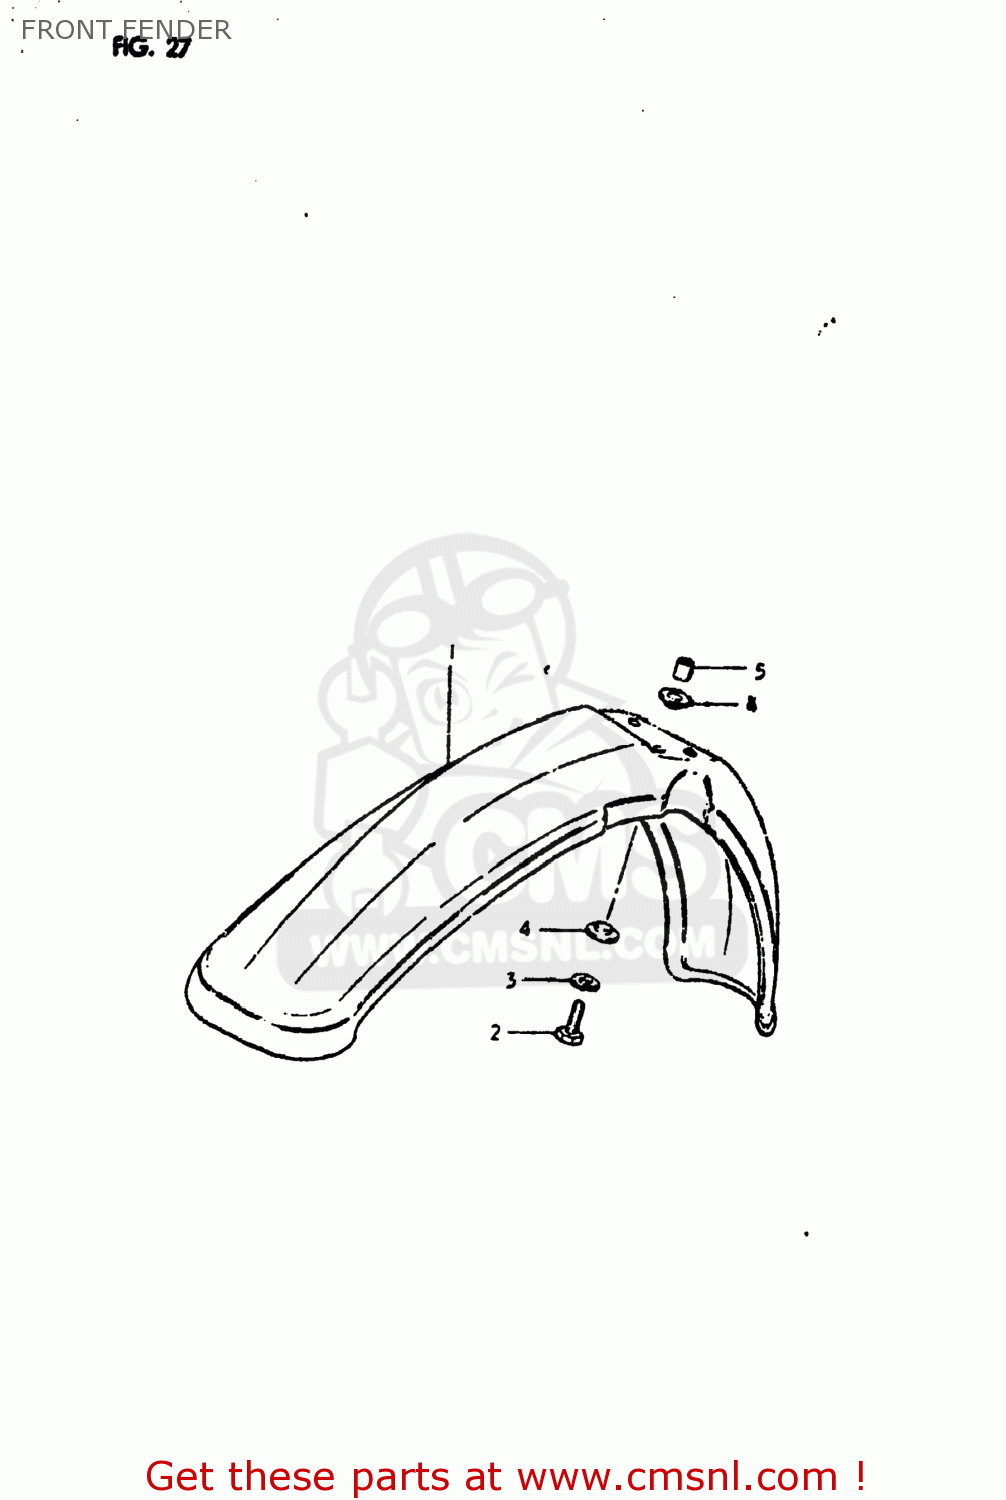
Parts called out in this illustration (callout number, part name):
1	FENDER,FRONT
2	BOLT
3	LOCK WASHER
4	SPACER
5	SPACER
